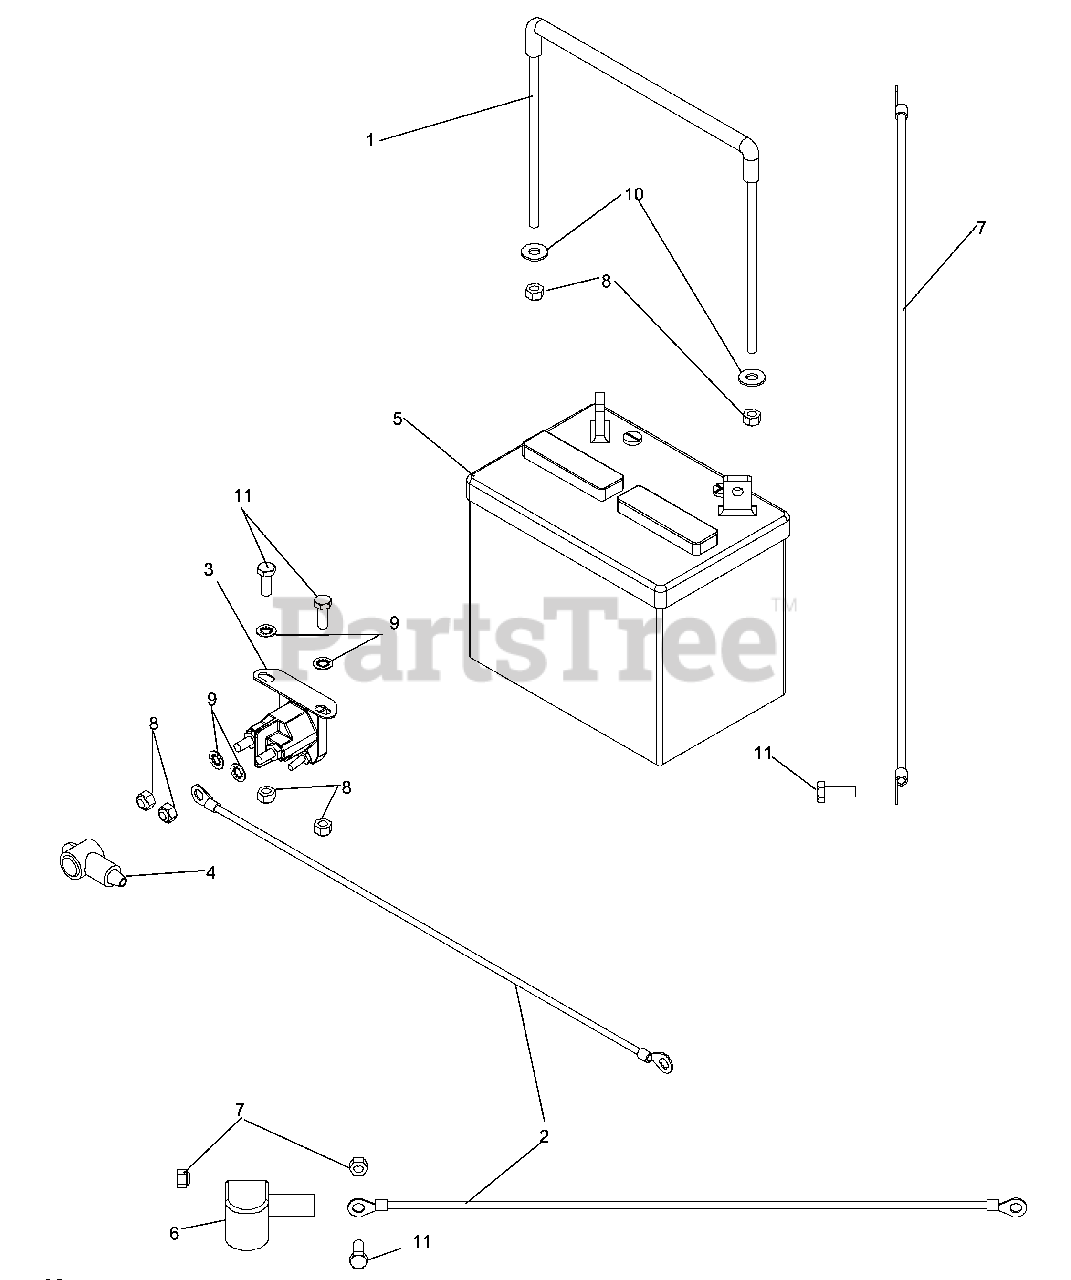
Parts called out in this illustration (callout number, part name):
1	TIE DOWN W/INSULATOR
2	SOL. TO STARTER CABLE
3	SOLENOID
4	TERMINAL COVER-SM
5	12V BATTERY
6	TERMINAL COVER
7	BATTERY CABLE, NEG
8	NUT 1/4-20 NYLOC
9	WASHER 1/4 INT TOOTH
10	FLAT WASHER 5/16 SAE
11	HCS 1/4C X 3/4 HCS
